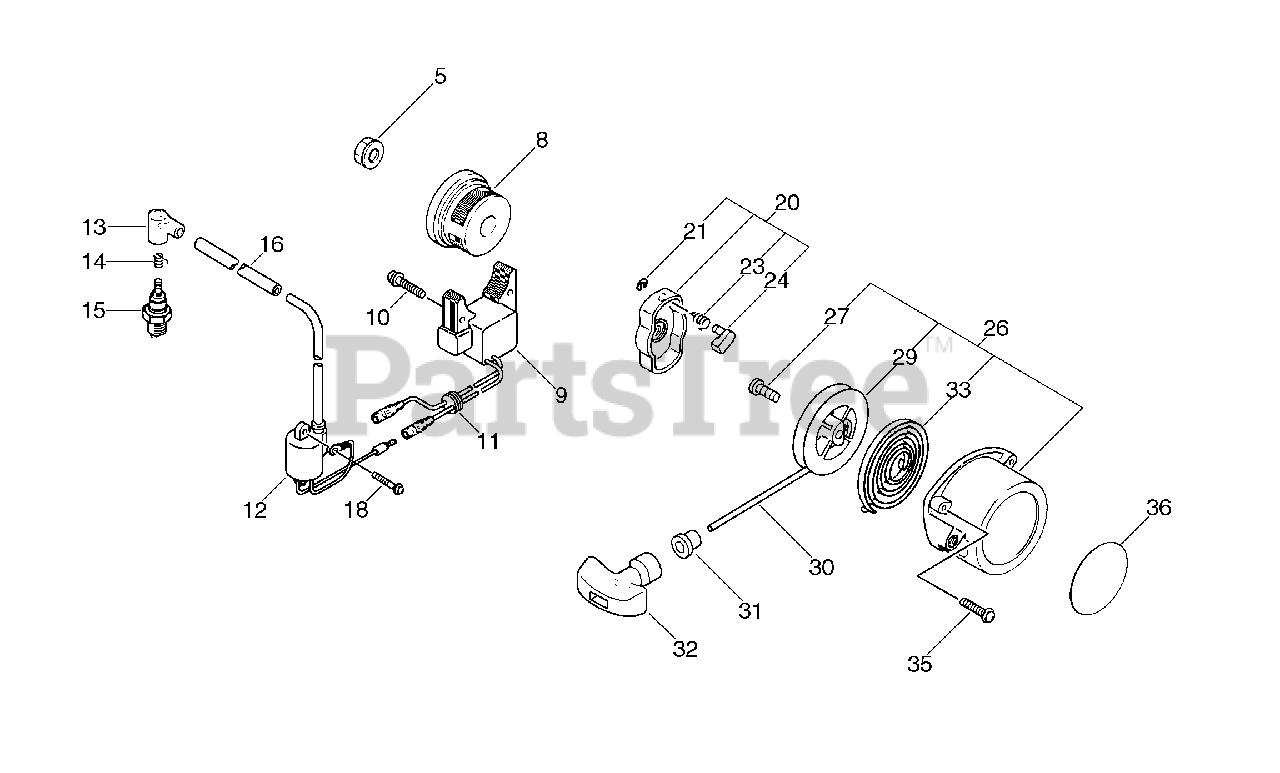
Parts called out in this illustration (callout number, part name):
5	NUT, FLANGE 10×1.25
8	FLYWHEEL
9	COIL, IGNITION
10	SCREW 5×25
12	COIL, IGNITION
13	CAP, SPARK PLUG
14	TERMINAL, SPARK PLUG
15	SPARK PLUG - BM6A
16	TUBE, INSULATOR
18	SCREW 4×16
20	PAWL CATCHER ASSY
21	E-RING 4
23	SPRING, RETURN
24	PAWL, STARTER
26	STARTER ASSY
27	SCREW
29	REEL, ROPE
30	ROPE, STARTER 4.0×880
31	GUIDE, ROPE
32	GRIP, STARTER
33	SPRING, RECOIL
35	SCREW 5×18
36	LABEL, ECHO
